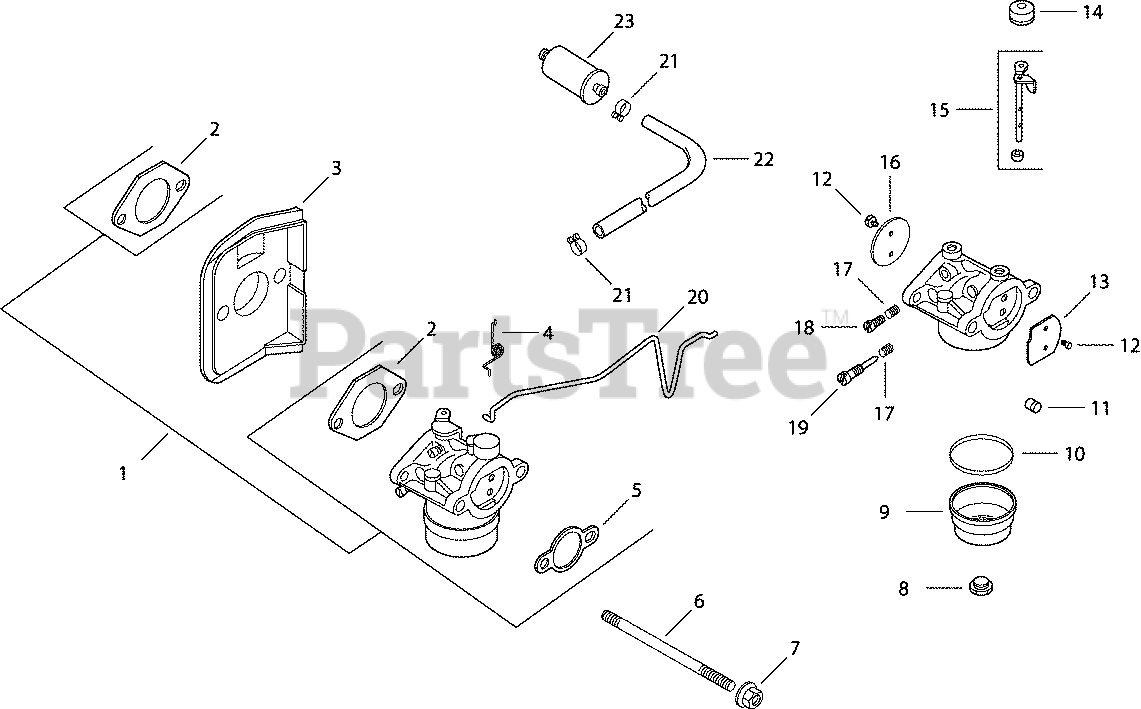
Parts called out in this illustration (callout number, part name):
1	KIT, CARBURETOR W/GASKET
2	GASKET, CARBURETOR
3	DEFLECTOR, HEAT
5	GASKET, AIR CLEANER BASE
6	STUD,M6X1.0X116
7	NUT, FLG M6X1.0
8	SCREW, FUEL BOWL RETAINER
10	GASKET, FUEL BOWL
11	JET, MAIN
12	SCREW, VALVE
13	PLATE, CHOKE
14	CAP, CHOKE LEVER
15	SHAFT, THROTTLE
19	NEEDLE, IDLE MIXTURE
20	LINKAGE, CHOKE
21	CLAMP, HOSE (KM)-USE 25 237 31-S
22	LINE, FLEXIBLE FUEL 9.0
23	FILTER, FUEL
